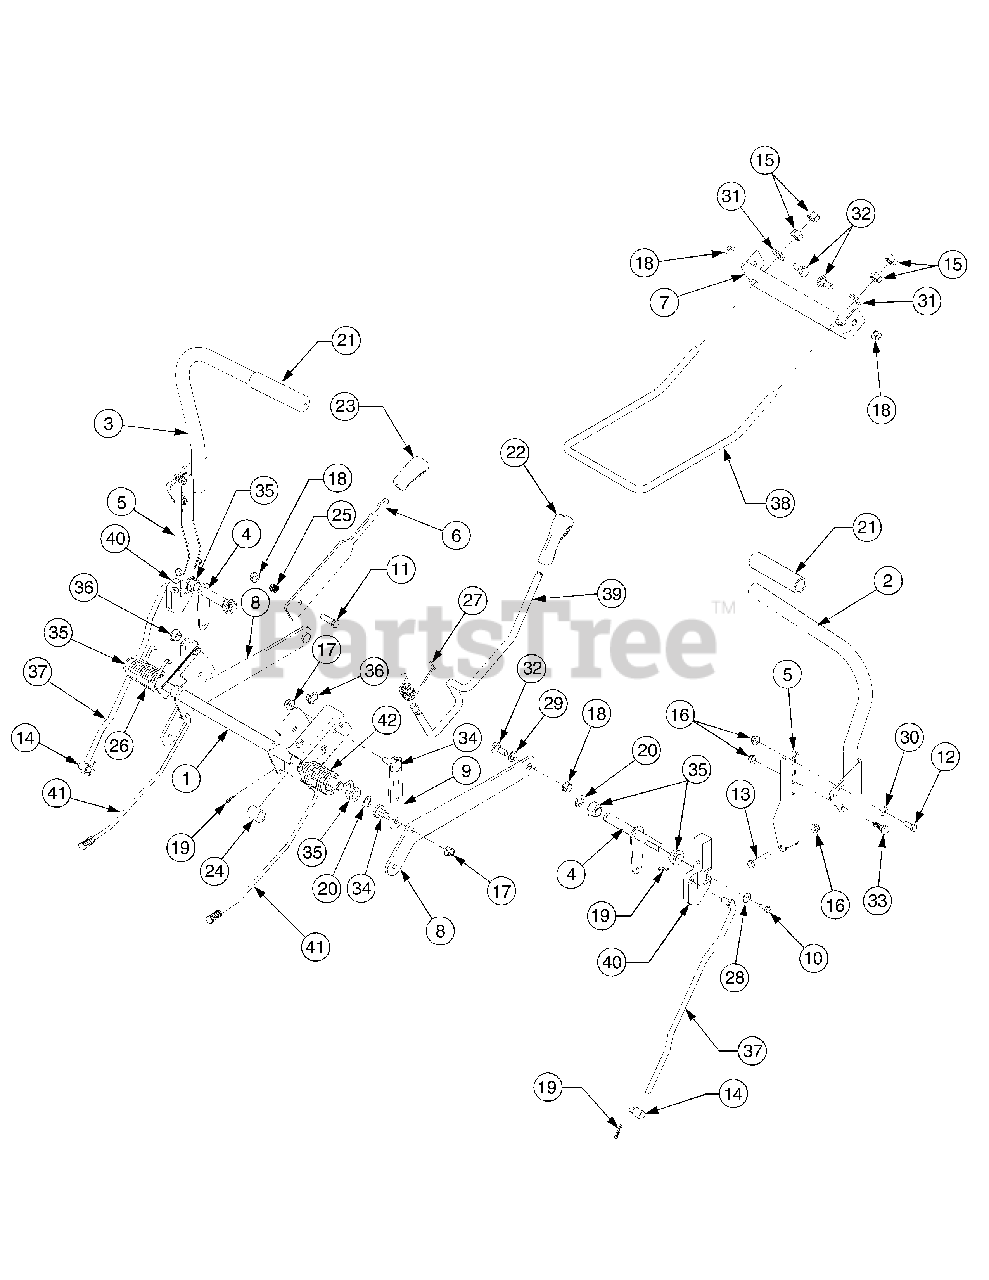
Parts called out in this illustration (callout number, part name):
5	Bracket, Lapbar Pivot
10	Screw, Hex Lock, 1/4-20 x .62 GR5
11	Screw, Hex Cap, 3/8-16 x 1.25 GR5
12	Screw, Hex Cap, 5/16-18 x .75 GR5
13	Screw, Hex Cap, 5/16-18 x 1.75 GR5
14	Ferrule, 3/8-24 x .375
15	Nut, Hex, 1/2-13 GR5
16	Nut, Hx Flange Insert Lck, 5/16-18 GrF
17	Nut, Hx Flange Insert Lck, 3/8-16GrF
18	Nut, Hex Flange Lock, 3/8-16 GRF
19	Pin, Internal Cotter
20	E-Ring , .625 Dia. Shaft
21	Grip, Hand
22	Grip, Handle
23	Grip, Handle
24	Spacer, .62 x 1.0
25	Spring, Compression
26	Spring, Torsion LH
27	Spring, Torsion RZT
28	Washer, Bell, .265 x .75 x .062
29	Washer, Flat, .51 x 1.0 x .06
30	Washer, Flat, .344 x .688 x .065
31	Washer, Flat, .531 x 1.062 x .134 HT
32	Screw, Shoulder, .498 x .340:3/8-16
33	Screw, Shoulder, .437 x .268:5/16-18
34	Screw, Shoulder, .5 x .434:3/8-16
35	Bearing, Hex Flange
36	Bearing, Flange, .626 x .938 x .344
37	Rod, Lapbar Control
38	Rod, Deck Front Hanger
39	Rod, Deck Lift Handle
40	Hub, Control
41	Rod, Brake
42	Spring, Torsion RH
